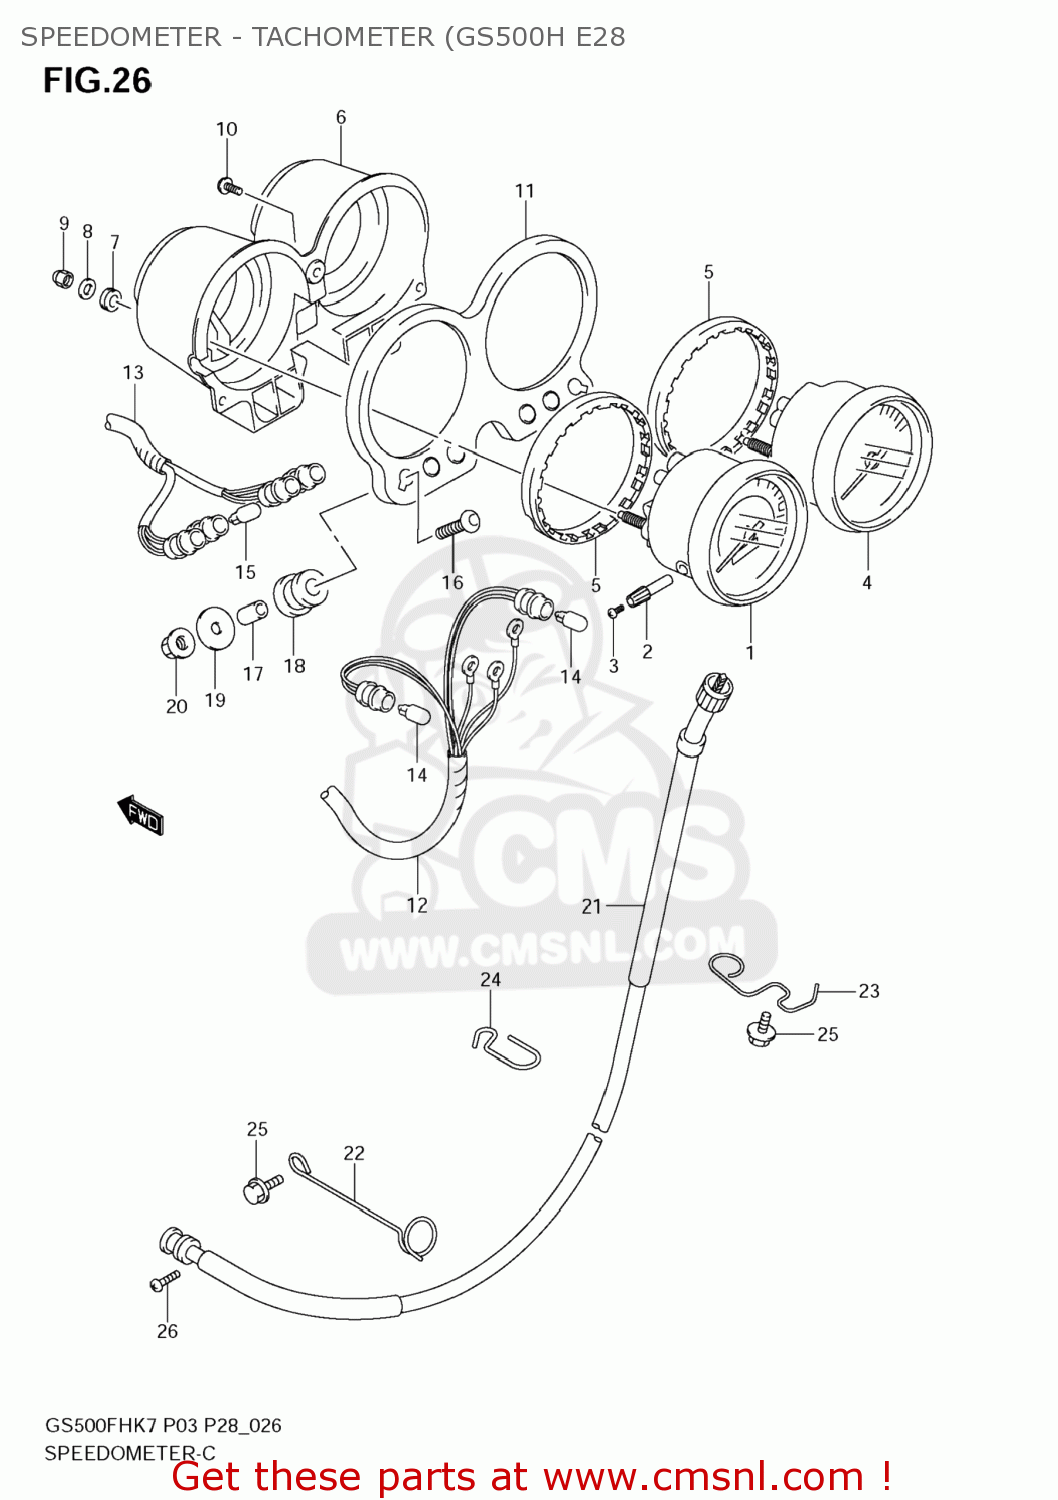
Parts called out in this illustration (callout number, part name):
1	SPEEDOMETER
2	KNOB
3	ROTOR,SPEED
4	TACHOMETER
5	DAMPER
6	COVER
7	CUSHION
8	WASHER
9	NUT
10	SCREW
11	BRACKET METER
12	SOCKET&CORD
13	SOCK.&CORD,PIL
14	BULB(12V1.7W,T10)
15	BULB (12V, 1.7W, T6.5)
16	BOLT(6X30)
17	SPACER(6.4X9X17)
18	CUSHION,METER BRACKET
19	WASHER(6.5X28X1.6)
20	NUT
21	CABLE ASSY,SPEEDOMETER
22	CLAMP,SPEEDOMETER CABLE
23	GUIDE,SPEEDOMETER CABLE NO.2
24	GUIDE,SPEEDOMETER CABLE NO.3
25	BOLT
26	SCREW
